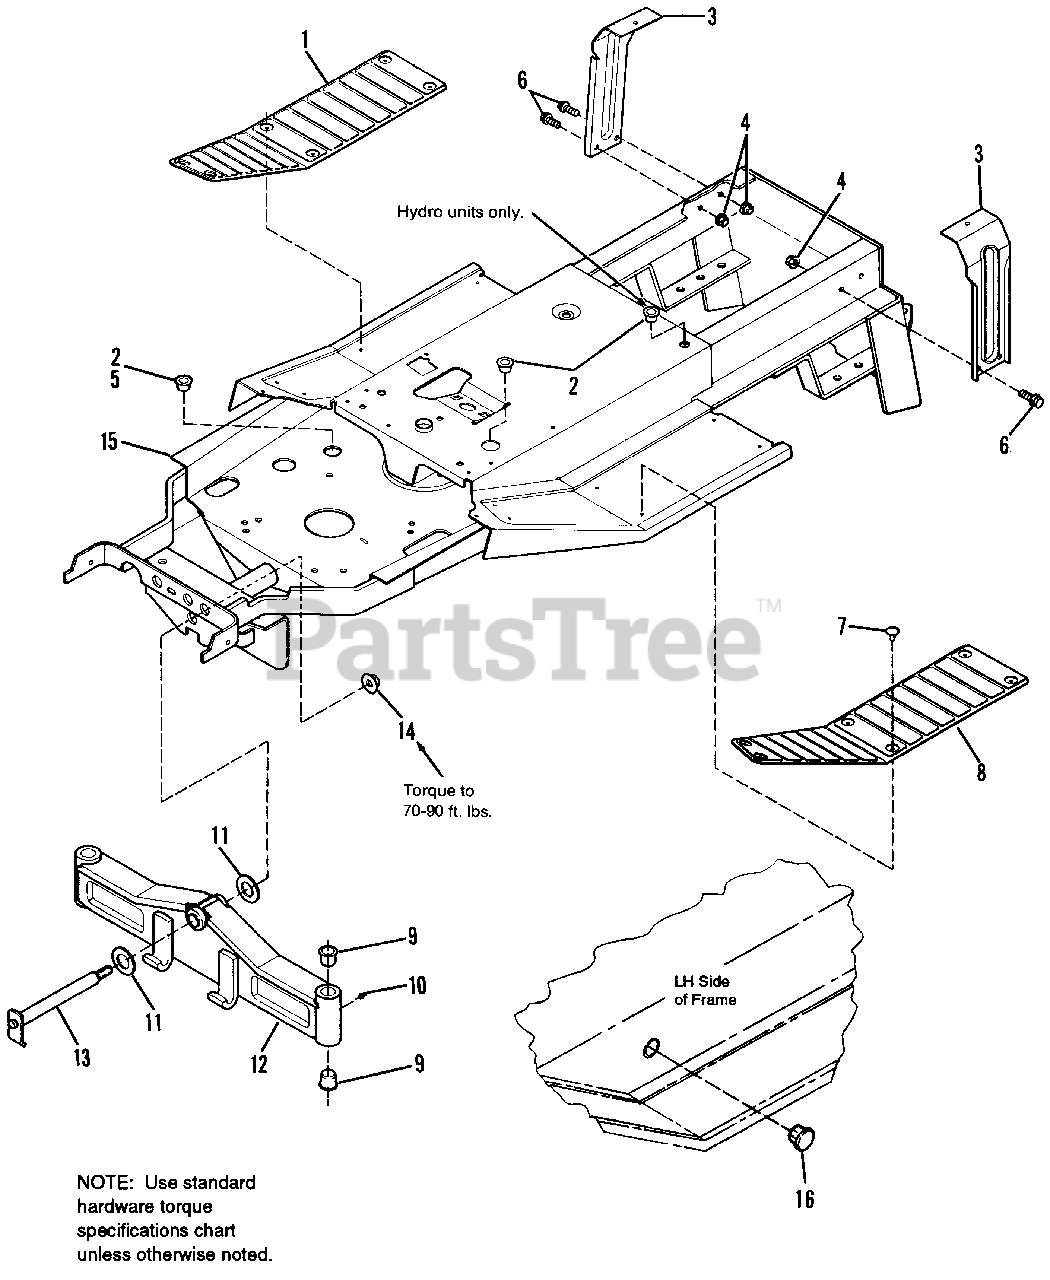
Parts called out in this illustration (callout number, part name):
1	PAD, Footrest, R.H.
2	BUSHING, Snap
3	SUPPORT, Seat
4	NUT, Hex, Esna Lock, 3/8-16
5	BUSHING, Snap (Gear only)
6	CAPSCREW, Hex Whizlock, 3/8-16 x 1
7	FASTENER, Panel
8	PAD, Footrest, L.H.
10	GREASE, Fitting
11	WASHER, Special
12	AXLE ASSY., Front
13	AXLE PIVOT ASSY.
14	NUT, Hex, Full Lock, 3/4-16
15	FRAME ASSY.
16	PLUG, Button
